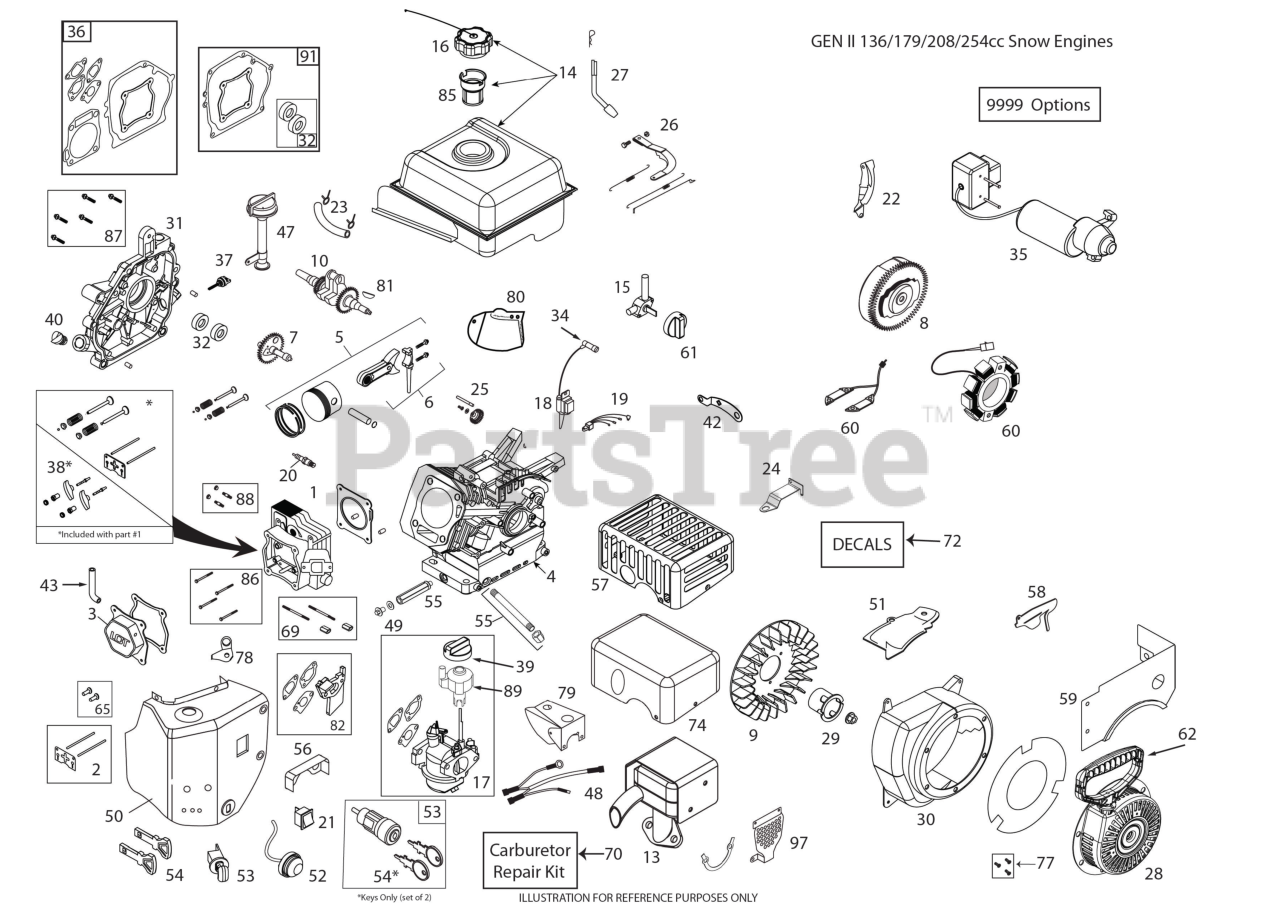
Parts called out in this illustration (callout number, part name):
1	CYLINDR.HEAD.SRV.KIT
2	KIT.PUSH.ROD.SRV(SK208-1001)
3	VALVE COVER ASSEMBLY
5	KIT.PISTON.SRV(SK208-1400)
7	KIT.CAMSHAFT.SRV(SK208-1600)
8	FLYWHEEL ELECTRIC START W/6 MA
9	KIT.COOLNG.FAN.SERV(SK208-4000
10	CRNKSHFT-KYD#14.208CCSKSNO8001
13	ASSY.MUFFLER.GENII.SKSN0201.1
14	FUEL.TK.ASSY.GENII.SKSN0311.1
15	FUEL.PETCOCK.SNOW(SKSN4900)
16	FUEL CAP OVERSIZED CLICK STYLE
17	CARB.GEN2.W/O.SPACER.LCT.208CC
18	208CC IGN COIL (STD)
20	SPARK.PLUG(2083810)
22	SHIELD.FLYWHEEL.ELEC.STRT.208C
23	FUEL HOSE KIT
24	SPEED.CTRL.BRKT.(SKSN0150)
25	GOVENOR.GEARS ASM(SK2082900)
26	CARBURETTOR GOVERNOR LINK.ASM.
27	KIT.GOVERNOR.CRANK(SK208-3100)
28	RECOIL.STRT.ROUND(BLK) SNOW
29	STRTER.CUP(NON-SLOT)SKSN0601.2
31	COVER CRANKCASE.LCT.SK2083605
32	SEAL KIT (2 PCS)
34	SPARK.PLUG.BOOT.SNW,SKSN4691.1
35	ELEC.START.GEN2.SKSN0400.2
36	GASKET.KIT.208CC(SK2084300.1)
37	DIPSTICK SMALL
38	ROCKER ARM KIT
39	CHOKE.KNOW.SNOW(SKSN4500)
40	NON REMOVABLE PLUG
43	TUBE.BREATHER.LCT.208
47	TUBE ASSY HIGH OIL-FILL
48	HARNESS WIRE. W/O OFF/ON SWITC
49	KIT.OIL.DRAIN.PLUG(SK2089911
50	BOX HEATER.W/O OFF/ON SWITCH.L
52	PRIMER.BULB.WITH HOSE (SNOW)
53	SWITH.KEY.ASSEM.SNOW.SINGLE.ST
54	KEY SET(2 KEYS) SKSN0407.1
55	EXTENDED OIL DRAIN TUBE
57	CE COMPLAINT.MUFLR.SKSN0202.1
58	SHIELD GOVENOR & CARB - COMPOS
59	FUEL.TNK.SKRT.GENII.SKSN0103.1
60	208CC 60W ALTERNATOR
61	FUEL KNOB-SNOW
65	TAPPET.KIT.LCT.208CC
69	CARB.STUDS & COUPLING KIT.SNOW
70	CARBURETOR.REPAIR KIT.LCT.
74	SHIELD HEAT SKSN0205.1
77	BOLT.KIT.RECOIL.LCT.ALL.ENGINE
81	KEYS.FLYWHEEL.208/414CC.5PACK
82	SPACER.CARBURETOR.208CC.LCT
85	STRAINER.FUEL.TANK.LCT.208CC
86	BOLT KIT.CYLINDER HEAD.LCT(4)1
87	KIT.BOLT.CRANKCASE.COVER.6PC
88	STUD.MUFFLER.KIT.LCT
91	COVER CRANKCASE GASKET
9999	HIGH.ALTITUDE.JET 6,000FT
9999	KIT.BOLT.LCT.SK9990.1
